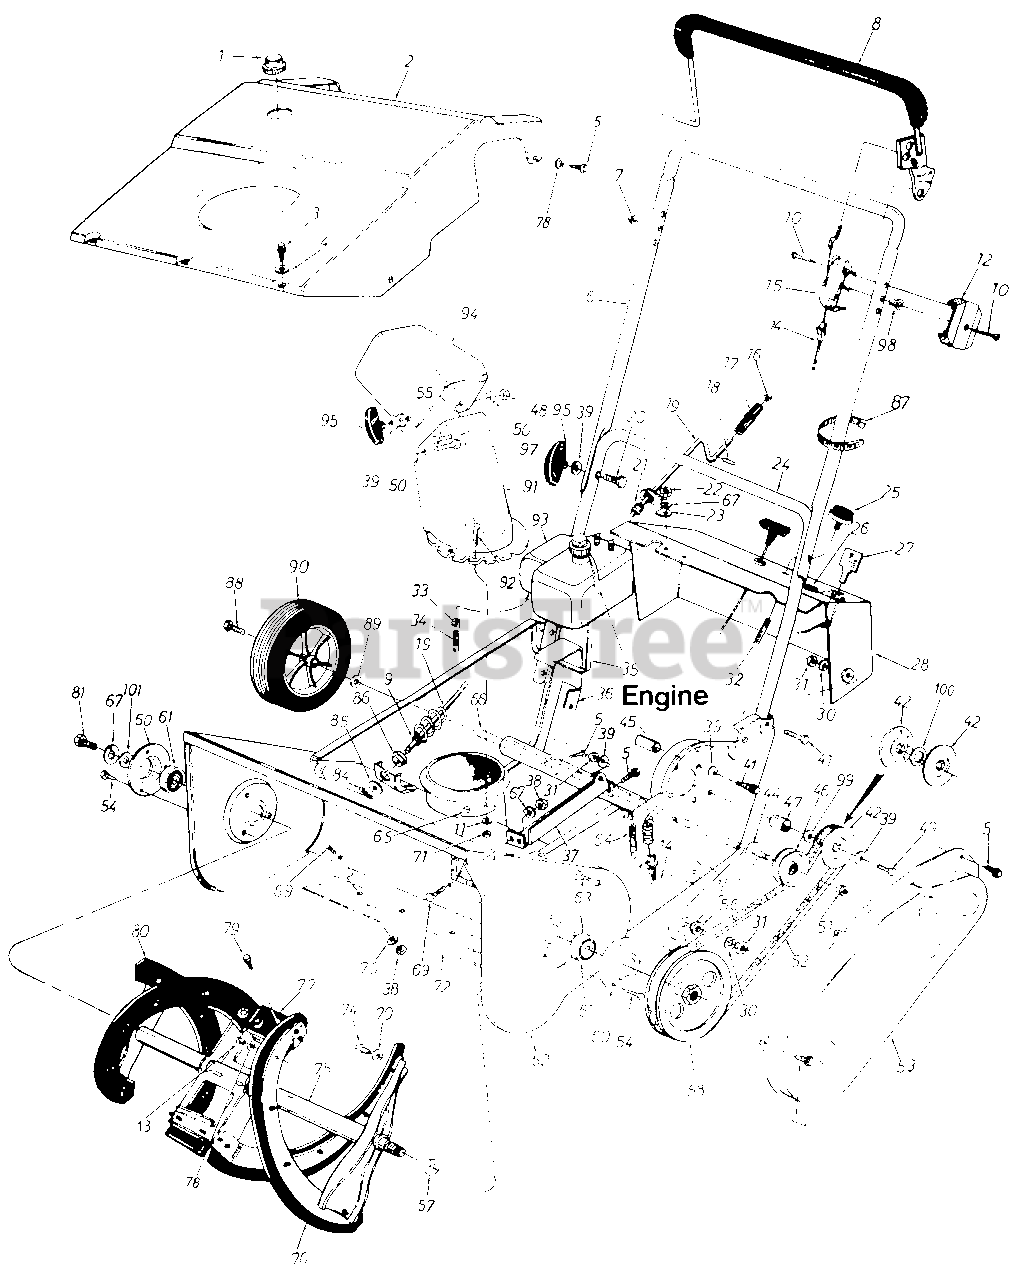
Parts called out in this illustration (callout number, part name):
1	Gas Tank Cap
2	21" Shroud
3	Hex B-Tap Scr. #10 x .38"
4	Spr.-Wash. .206" l.D. x .448"
5	Hex L-Wash. Hd. AB-Tap 1/4 x .62" Lg.
8	Control Handle Ass'y.-L.H.
9	Fl-Wash. .385" I.D. x .62"
10	Truss Mach. Hi-B 0 Tap Scr. #12 x 1.5" Lg.
11	Fl-Wash. .281" l.D. x .5" O.D.
12	Control Panel Half
13	Pop Rivet .188" Dia.
14	Clutch Cable 35" Lg.
15	Control Panel Half
16	Push Cap .818" Rod
17	Knob-3/8" Dia. Hole
18	Roll Pin 1/8" Dia. x .63" Lg.
19	Chute Crank Ass'y.
20	Curved Carriage Bolt 5/16-18 x 1.75" Lg.
21	Chute Crank Grommet
22	Hex Nut 1/4-20 Thd.
23	Upper Chute Crank Brkt.
24	Lower Handle
26	Plastic Plug
27	Plastic Key
31	Hex Nut 5/16-18 Thd.
32	Primer Hose-11" Lg.
33	Hose Clamp-1/2" Dia.
34	Gas Line-12" Lg.
35	Cable Tie-17.75" Lg.
36	Engine Support Brkt.
37	Engine Support
38	Hex Jam Nut 1/4-20 Thd.
39	Bell-Wash. .345" I.D. x .88"
41	Hex Bolt 5/16-18 x 1.5" Lg.
42	3/8" "V"-Pulley Half .625" l.D. x 6.0" O.D.
44	Idler Brake Brkt. Ass'y.
45	Spacer.325" l.D. x .625" O.D. x .875"
46	Fl-ldler w/Flanges 2.12" O.D.
47	Spacer.635" I.D. x .89" O.D. x .57
48	Hex L-Nut 5/16-18 Thd.
49	Hex Bolt 5/16-24 x .75" Lg.
50	Fl-Wash. .344" I.D. x 1.25"
51	Hex Patch L-Nut 3/8-24 Thd.
52	V-Belt
54	Hex B-Tap Scr. 1/4" x .38" Lg.
55	Carriage Bolt 5/16-18 x .75"
56	Shld. Spacer .50" Dia. x .27"
57	Fl-Wash. .510" I.D. x l.0" O.D.
58	3/8" "V"-Pulley 1/2-20 L.H. x 6"
60	Bearing Cup
61	Ball Brg. .669" I.D. x 1.574"
64	Extension Spring 1.12" Lg.
65	Chute Flange Keeper
66	Wheel Axle 1/2" O.D. x 20.6" Lg.
67	L-Wash. l/4" l.D.
69	Carriage Bolt 1/4-20 x .50
70	Fl-Wash. .281" l.D. x .73"
71	Hex L-Nut 1/4-20 Thd.
72	Shave Plate
74	Hex Wash. B-Tap Scr. 1/4 X .62n
75	Auger Ass'y. 21n
76	Rubber Spiral-L.H.
77	Rubber Paddle
78	Fl-Wash. .218" l.D. x .62"
79	Hex Wash. B-Tap Scr. #1 62" Lg
80	Rubber Spiral-R.H.
81	Hex Wash. TT-Tap Cl-Scr. 1/4-20 x .75" Lg.
84	Cotter Pin 3/32" Dia. x .75"
85	Fl-Wash. .406" l.D. x 1.25n
86	Hex Bushing .385" I.D.
87	Cable Tie
88	Hex Tap Scr. 3/8-24 x .88" Lg.
89	Fl-Wash. .510" I.D. x.75"
90	Wheel & Tire Ass'y. 7" x 1.5n
91	Lower Chute
92	Truss Mach. Scr. 1/4-20 x .75n
93	Fuel Tank-Two Qt.
94	Upper Chute
95	Knob Handle Ass'y.
97	Carriage Bolt 5/16-18 x 1"
98	Control Disc Pin
99	Fl-Wash. .635" l.D. x 1 .04" O.D.
100	Fl-Wash. .635" l.D. x 1.0" O.D.
101	Fl-Wash. .25" I.D. x .93"
